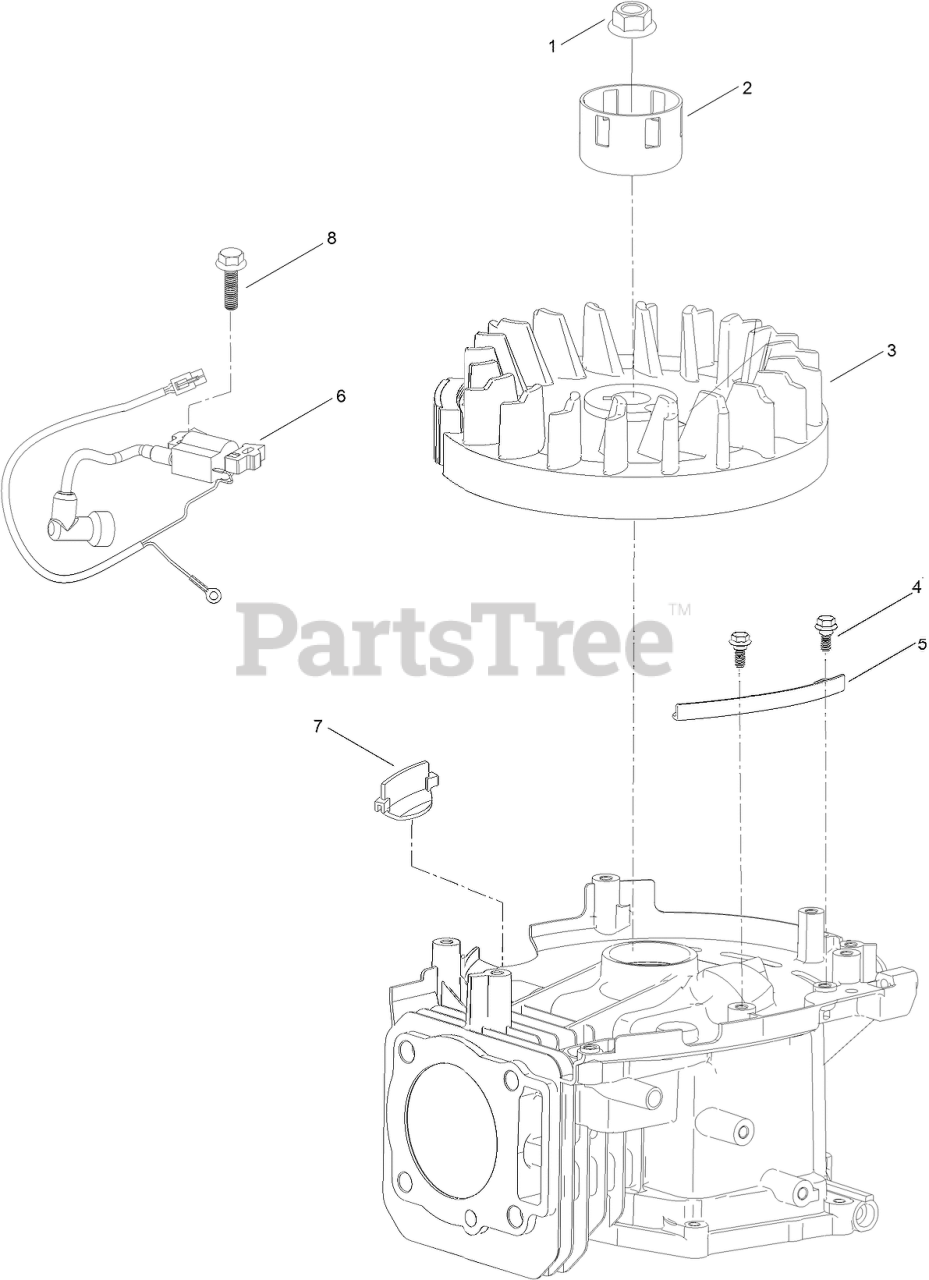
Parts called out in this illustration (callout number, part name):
1	NUT-FLANGE
2	CUP-STARTER
3	FLYWHEEL
4	SCREW-SHOULDER, HHF
5	GUARD-FLYWHEEL
6	COIL-IGNITION
7	GUARD-FLYWHEEL
8	SCREW-HHF
